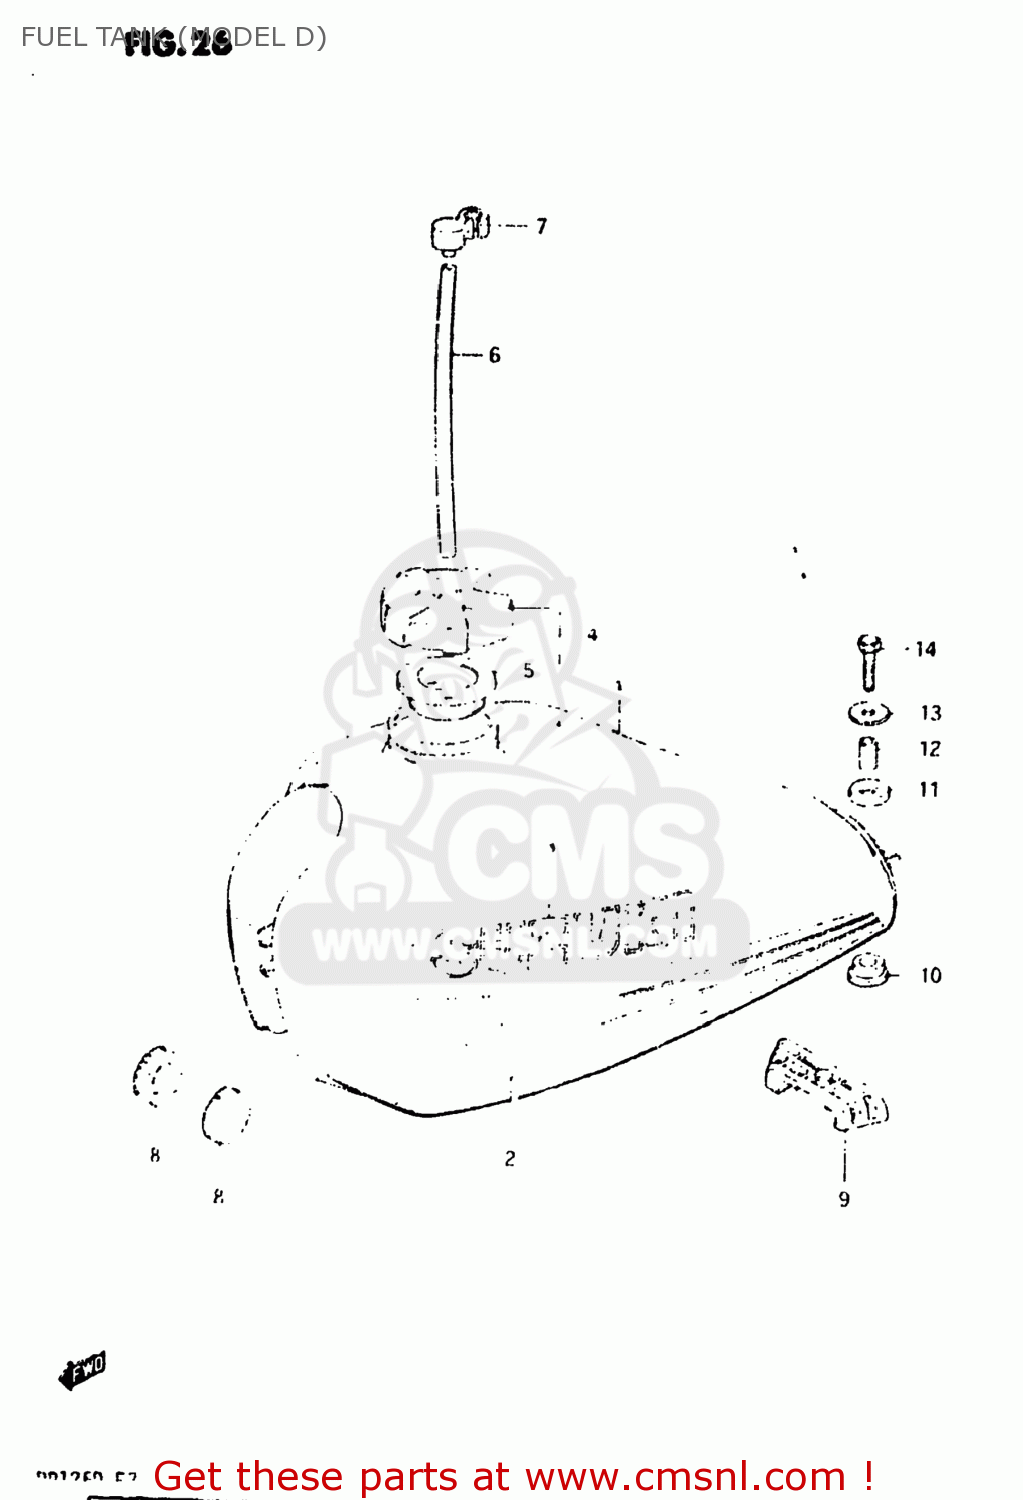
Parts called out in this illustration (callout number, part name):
1	TANK ASSEMBLY,FUEL
2	TAPE SET,FUEL TANK
3	EMBLEM
4	CAP SET,FUEL TANK
5	GASKET (NAS)
6	HOSE
7	CLAMP,FUEL TANK BREATHER HOSE
8	CUSHION
9	CUSHION,FUEL TANK
10	CUSHION
11	CUSHION
12	SPACER(8.5X12X19)
13	WASHER (8.5X29X1.6)
14	BOLT (8X30)
